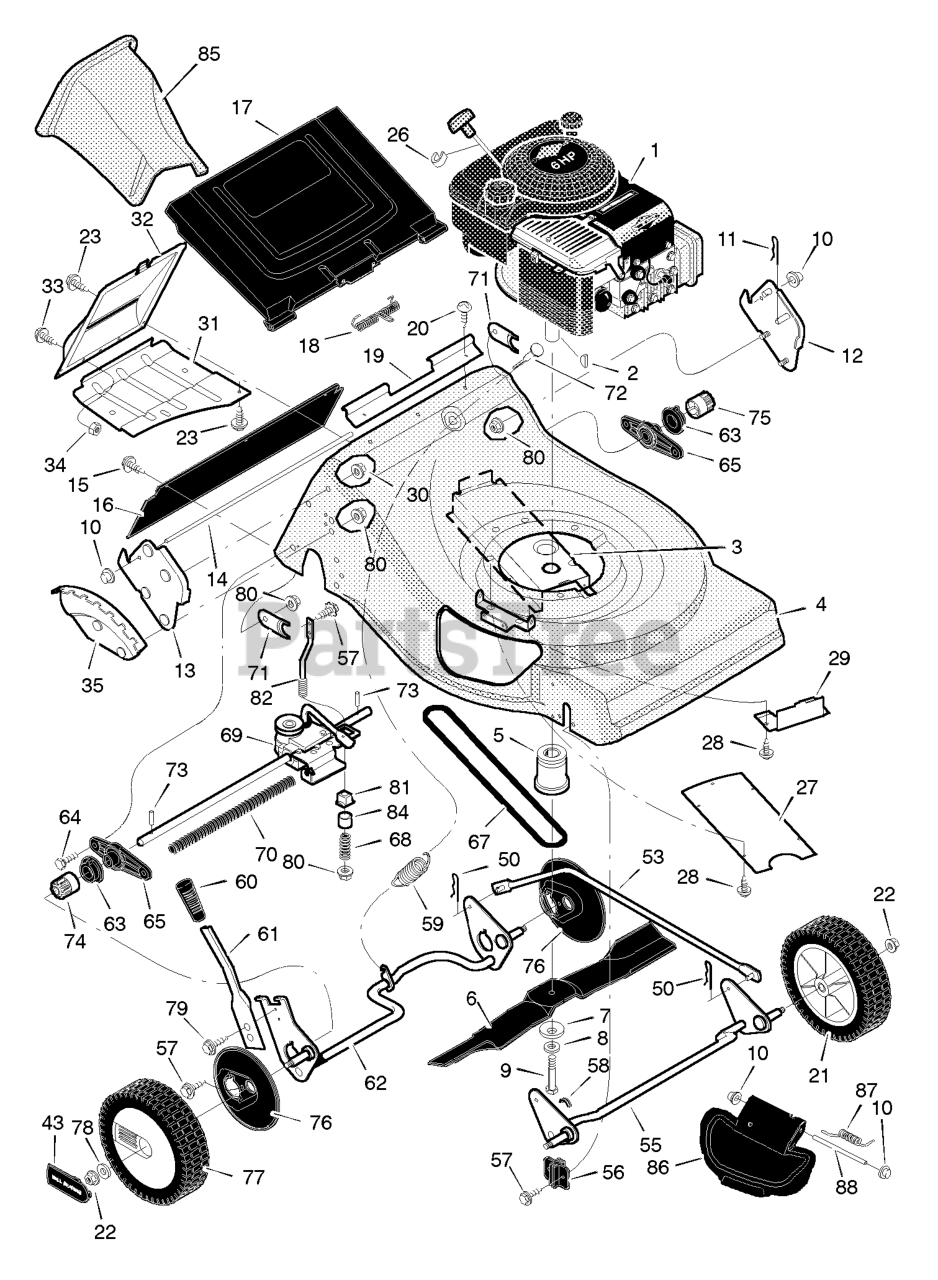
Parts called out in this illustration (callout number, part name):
1	Engine *
2	Key, Woodruff
3	Bolt, Engine
4	Housing
5	Adapter, Blade
7	Washer, Belleville
10	Push On Cap
11	Pin, Hair
12	Handle Bracket, Left
13	Handle Bracket, Right
14	Rod, Door Pivot
16	Deflector, Rear
17	Door, Rear
18	Spring, Torsion
19	Spacer, Door
21	WHEEL & TIRE ASSEMBLY, White, 8"
22	Nut
26	Stop, Rope
27	Cover, Belt
29	Cover, Front Belt
30	Nut, Hex Flange
31	Cover, Lower
32	Cover, Rear
33	Screw
35	Bracket, Index
43	Hub Cap
53	Link, Lifter
55	Crossbar, Front
56	Clip, Retainer
58	Bushing
59	Spring, Extension
60	Grip, Height Adjuster
61	Lever, Height Adjuster
62	Crossbar, Rear
63	Bearing, Lifter
64	Bolt, Hex
65	Support, Axle
67	Belt, Drive
68	Spring
69	Transmission TIM .50
70	Shield, Axle
71	Retainer, Bearing
72	Support, Lifter Spring
73	Pin, Drive
74	Pinion, Right
75	Pinion, Left
76	Cover, Dust
77	Wheel, Drive - White
78	Washer, Thrust
80	Locknut
81	Bushing
82	Support, Spring
85	Plug, Mulcher
86	Cover, Mulch
87	Spring, Torsion
